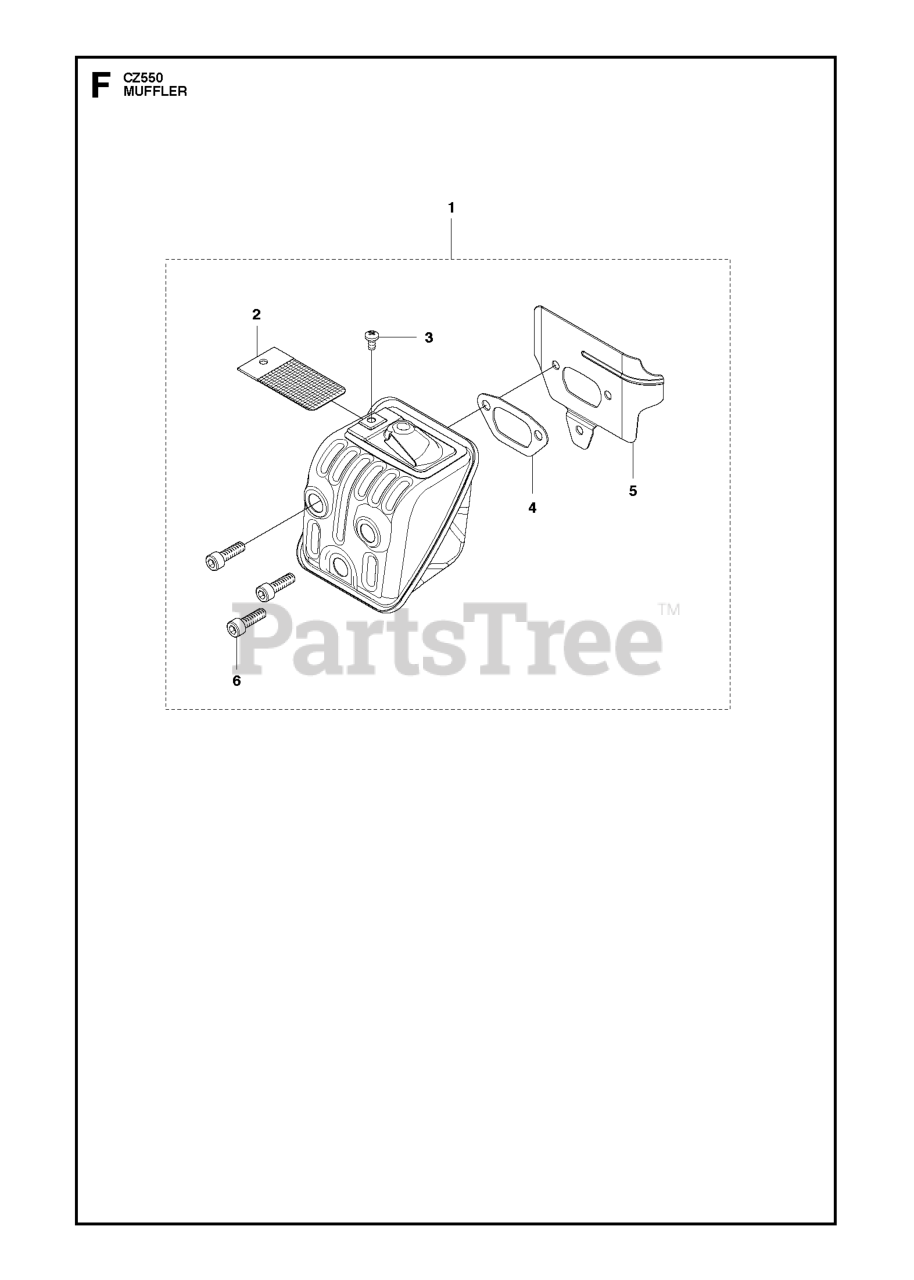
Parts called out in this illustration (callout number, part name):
1	MUFFLER KIT
2	SPARK ARRESTOR SCREEN
3	SCREW CRPANM
5	HEAT DEFLECTOR
6	SCREW MC6S 6X20
